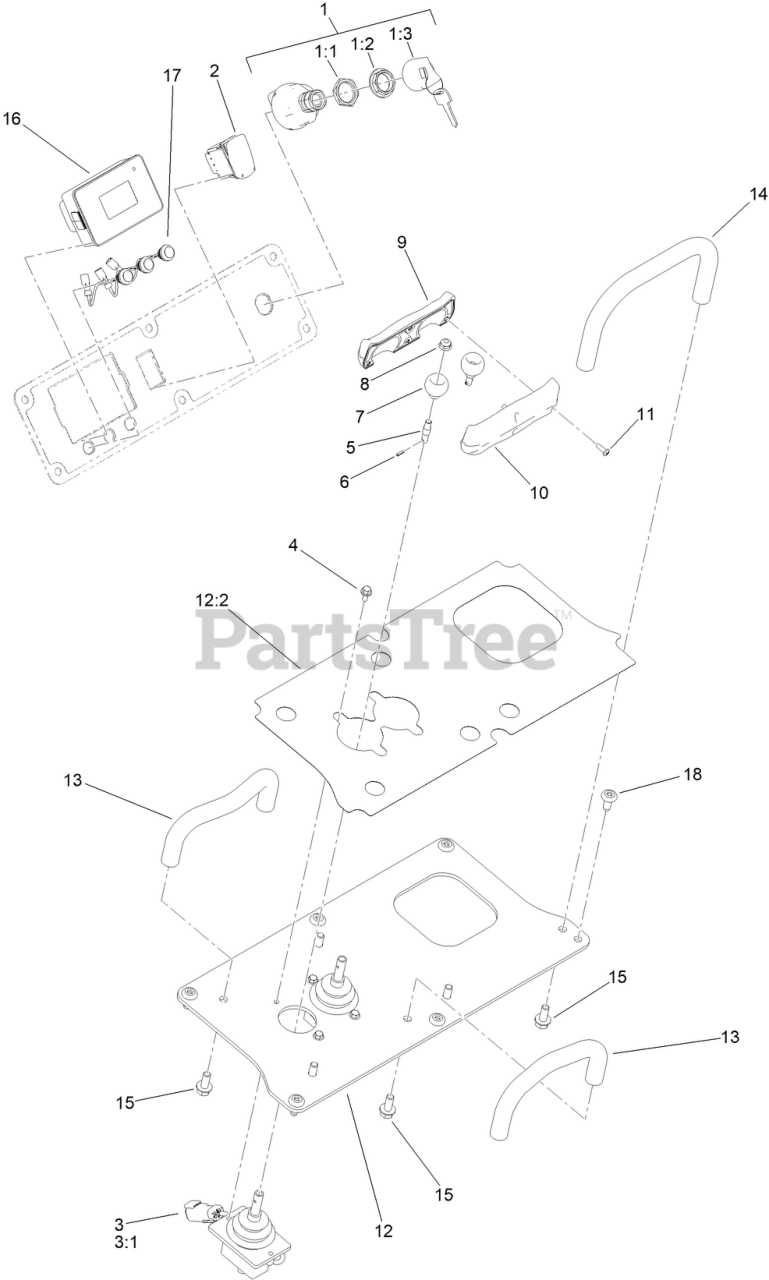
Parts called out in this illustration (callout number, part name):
1	SWITCH-IGNITION, SUNS
1:2	NUT-FACE, M22 (PLASTIC)
1:3	SET-KEY, IGNITION
2	SWITCH
3	LEVER-CONTROL
3:1	LEVER-CONTROL, JOYSTICK
4	SCREW-HFH
5	SHAFT-HANDLE
6	PIN-ROLL
7	BALL-TRACTION
8	NUT-HF
9	HANDLE-FRONT
10	HANDLE-REAR
11	SCREW
12	PANEL-CONTROLS
12:2	DECAL - CONTROL PANEL
13	BAR-REFERENCE
14	BAR-REFERENCE
15	SCREW-HHF
16	CONTROLLER, TDM-1601
17	SWITCH-PUSHBUTTON
